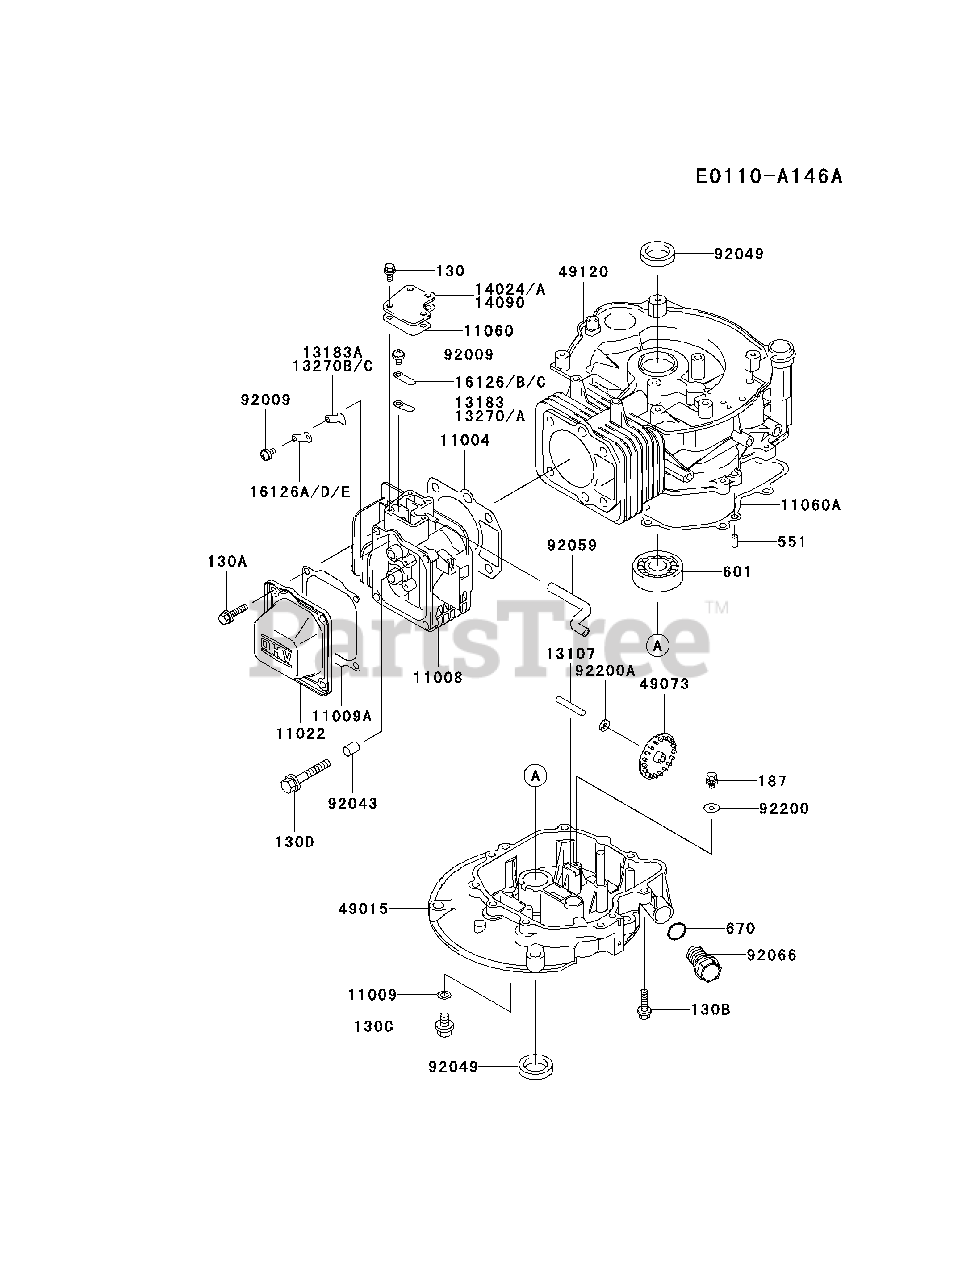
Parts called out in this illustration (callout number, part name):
130	BOLT-FLANGED
130A	BOLT-FLANGED
130B	BOLT-FLANGED
130C	BOLT-FLANGED
130D	BOLT-FLANGED
187	BOLT-UPSET-WSP
551	PIN-DOWEL
601	BEARING-BALL
92200A	WASHER,6X12X1.6
